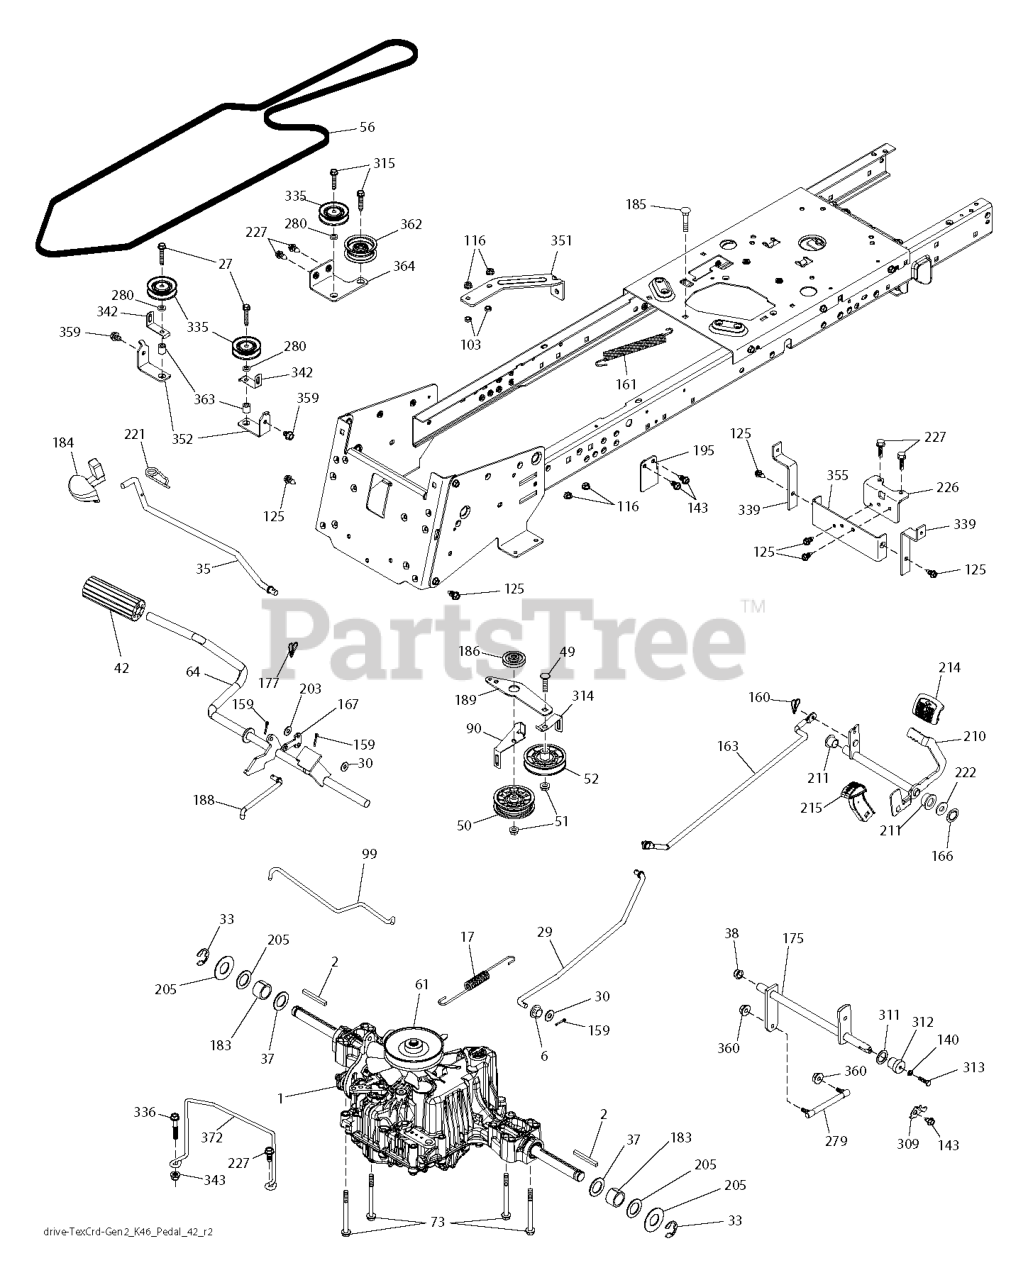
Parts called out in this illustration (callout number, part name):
2	SQUARE KEY
6	BUSHING.SNAP.NYL.BLK.
17	SPRING
29	ROD ROD BRAKE K46 TCRD GEN 2
37	WASHER.HARDENED
38	NYLINER SNAP 5/8" ID
42	PEDAL COVER
50	IDLER.FLAT.910.OFFSET
51	NUT LOCK FLG 3/8-16 UNC
52	IDLER.V-GROOVE.910.OFFSET
56	BELT.DRIVE.CRD.GENII.EURO.HYDR
61	PULLEY PULLEY INPUT FLANGED TR
64	SHAFT.ASM.PEDAL.BRK.CNTR
90	KEEPER KEEPER BELT CLUTCHING T
99	ROD ROD BYPASS CRD TEX GEN 2
125	SCREW
140	WASHER SPRING LOCK WASHER WITH
160	GSPW Retainers
161	SPRING, RETURN LT
166	NUT.PUSH.625
167	LATCH.BRAKE.SPRING
175	SHAFT SUBASM.SHAFT.CROSS.SHIFT
177	PIN COTTER;LOCKING;BOWTIE;1IN
183	SPACER AXLE
184	HANDLE.PARKING.BRAKE.H (BLK)
186	SPACER.RETAINER
188	LINK.CLUTCH.GROUND DRIVE.LONG
189	BELLCRANK BELLCRANK GROUNDDRI
195	BRACKET.ROD.BRAKE
203	WASHER 11/32 X 11/16 X 14 GA T
210	ROCKER.ASM.PEDAL.CONTR
211	BEARING.NYLON
214	PEDAL.FORWARD.PAD.TEX
215	PEDAL.COVER.REVERSE.CRD.X428BK
221	RETAINER.SPRING.CLIP.H
222	WASHER 21/32 X 1-1/4 X 10 GA.
226	BRACKET.MOUNT.TORQUE.K46.TLT
309	PLATE FASTENING LT
311	WASHER NYL
312	HUB.TAPERED.ROUND.CRD
314	RETAINER KEEPER BELT
315	BOLT.5/16-18X1.25
335	PULLEY.V-IDLER.
339	STRAP STRAP TORQUE K46 CRD TE
342	BELT GUIDE
343	NUT HEXAGON FLANGE 5/16-18 ST
351	BRACKET BRACKET DECK SWAY
352	BRACKET BRACKET IDLER CRD TEX
355	STRAP STRAP TORQUE K46 CRD TEX
360	NUT NUT HEX CENTERLOCK 5/16-24
362	IDLER.FLAT.2.25.INCH
363	SPACER SPACER 343X63X.62
364	BRACKET BRACKET IDLER CRD TEX
372	KEEPER.BELT.CRD2.K46.2.BOLT.
